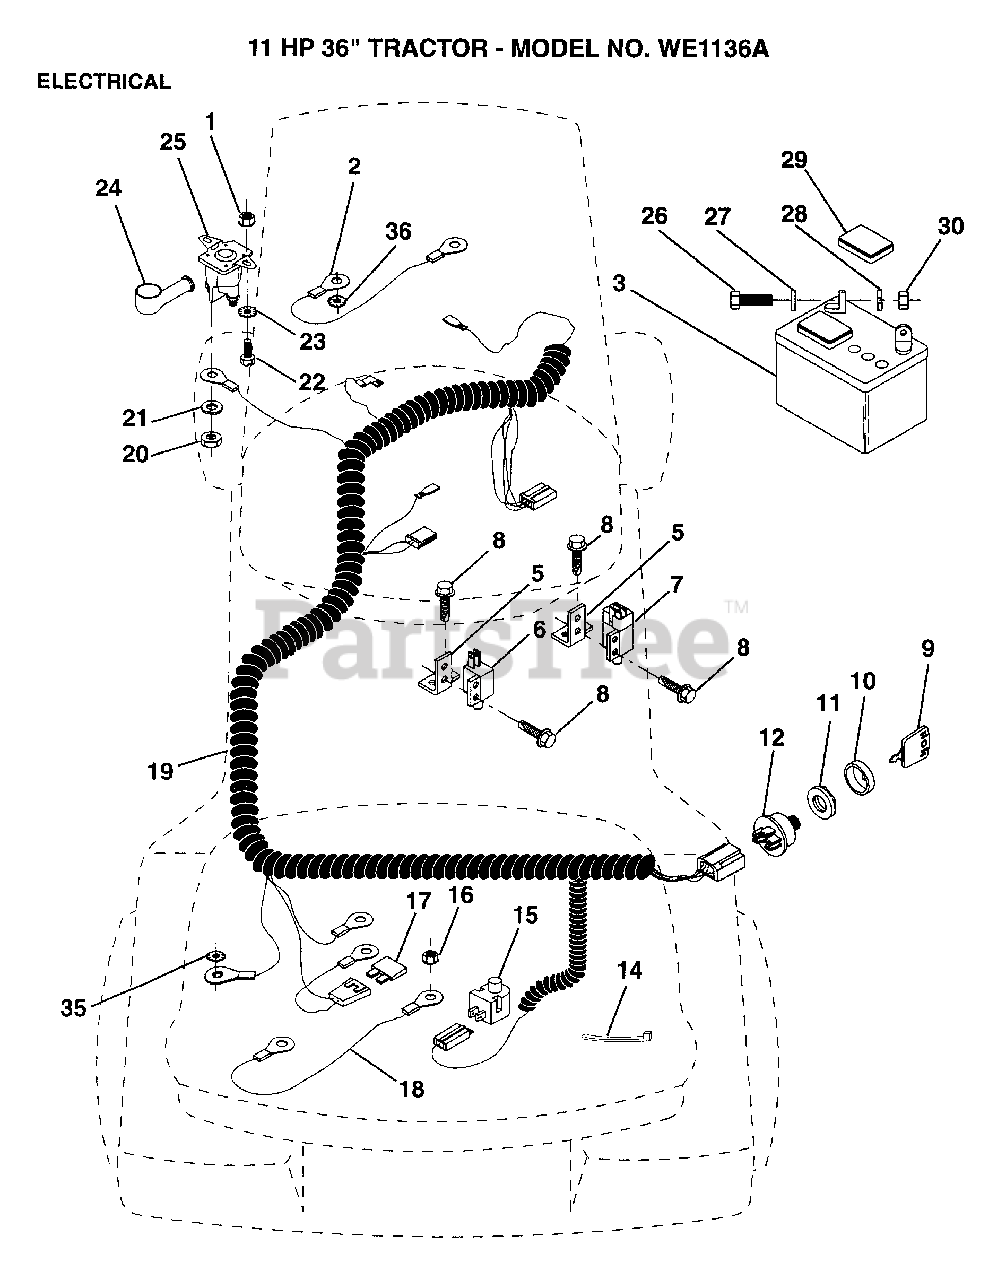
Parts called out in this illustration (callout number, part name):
1	NUT
2	CABLE ASM.
5	BRACKET LT
6	SWITCH-INTER. GT
7	SWITCH INTERLOCKT
8	SCREW
9	KEY
11	NUT IGNITION
14	WIRE TIE
15	SWITCH SEAT
17	FUSE HYT
18	CABLE ASSY
20	NUT
22	BOLT
26	BOLT LT
27	WASHER
28	LOCKWASHER
29	"CAP,BATTERY "
35	LOCKWASHER
36	LOCKWASHER
